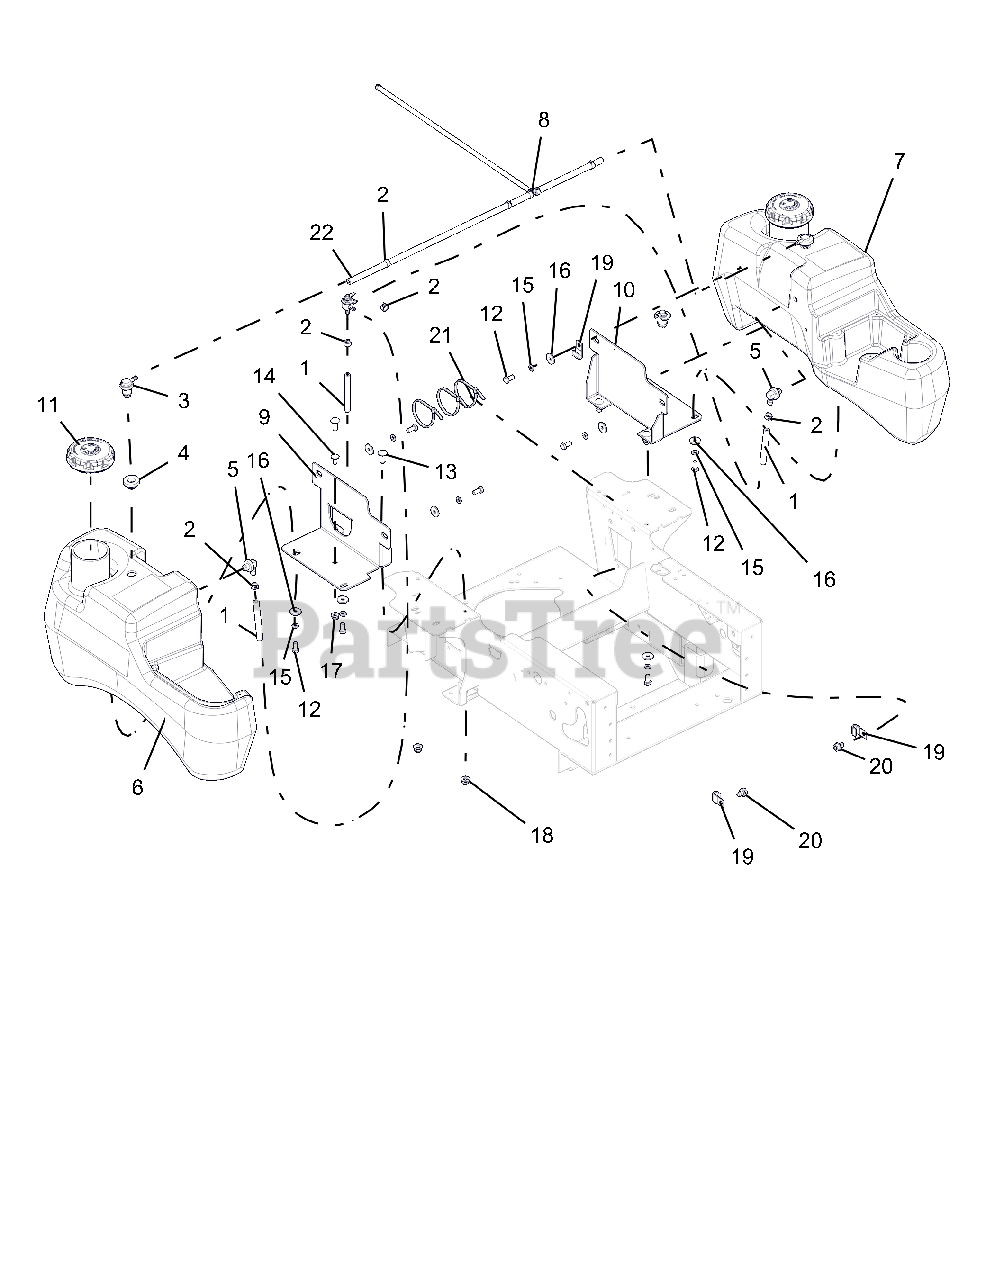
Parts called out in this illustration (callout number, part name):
1	.25 LOW-PERM GAS HOSE
2	CLAMP, FUEL LINE
3	VALVE, COMBINATION
4	GROMMET, REMOTE VENT NITRILE
5	ASS'Y, SMALL/ MED TANK FUEL PICK-UP
6	TANK, GAS - RH MEDIUM GRAVELY
7	TANK, GAS - LH MEDIUM GRAVELY
8	PT100, KAW FUEL LINE ASSEMBLY
9	BRKT, RH MEDIUM FUEL TANK MTG
10	BRKT, RH MEDIUM FUEL TANK MTG
11	CAP, FUEL VENT-IN AUTOLOCK
12	BLT-HEX .31-18X.75 GR5 YWZC
13	BLT-RDHDSHSQNK.38-16X1.0 G5YZ
14	BLT-RDHDSQNK .31-18X.75 G5 YWZC
15	WSHR-LK .31X.078 REG YWZC
16	WSHR-FL-STL .328X1.00X.094 YWZC
17	NUT-LK-NYL-FLG .31-18 YWZC
18	NUT-LK-NYL-FLG .38-16 YWZC
19	CLAMP, J
20	SCR-TAP .38-16X.50 HWH TR YWZ
21	CABLE, TIE 5.50 LG
22	VALVE, FUEL
